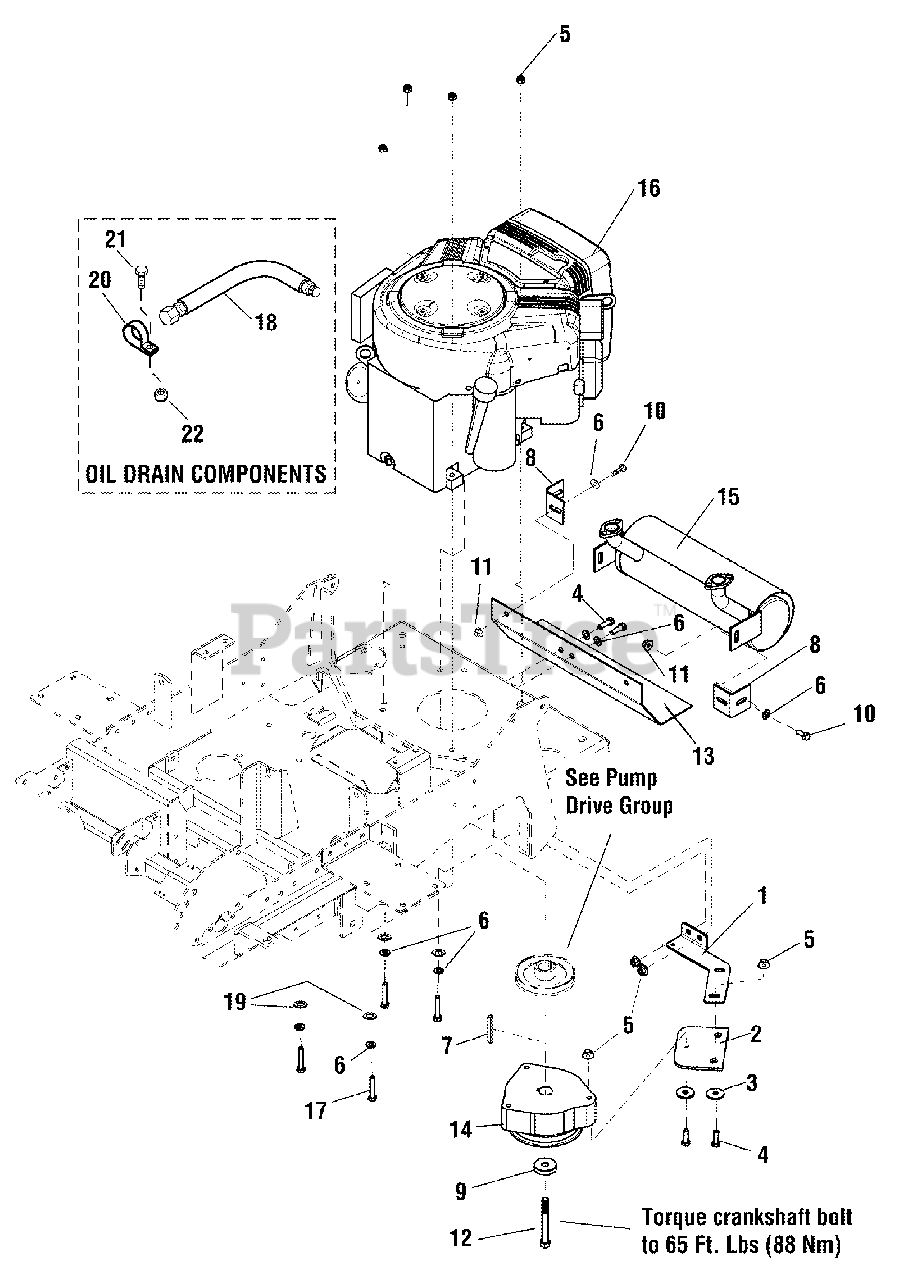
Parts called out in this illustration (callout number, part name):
1	PLATE, CLUTCH ANCHOR - RED
2	CLUTCH ANCHOR PAD
3	WASHER, .34 X 1.25 X 10 GA
4	BOLT, 5/16-18 X 1 GD5 YZ
5	NUT, 5/16-18 HEX NYLOCK FLANGE
6	WASHER, 5/16" SAE
7	KEY, 1/4" SQ. X 2 1/4
8	BRACKET, SUPPORT, MUFFLER
9	SPACER, .45 X 1.62 X .37
10	BOLT, 5/16-18 X 3/4 GD5
11	NUT, 5/16-18 HEX SERRATED FLANGE (LARGE)
12	CAPSCREW, CRANKSHAFT, 7/16-20 x 3-1/4,YZ
13	PLATE, HEAT SHIELD - RED
14	CLUTCH, #51110100,ELECTRIC, 1 SHAFT
15	MUFFLER, ACS - 20HP BRIGGS
16	* ENGINE, 20 HP BRIGGS VANGUARD, Mod. 358777-0120-G1
17	BOLT, 5/16-18 X 2-1/4 GD5 YZ
18	HOSE, OIL DRAIN
19	WASHER, 5/16 INT. TOOTH LOCK
20	CLAMP, VINYL INSULATED
21	BOLT, 1/4-20 X 3/4 GD5 YZ
22	NUT, 1/4-20 HEX SERR. FLANGE
